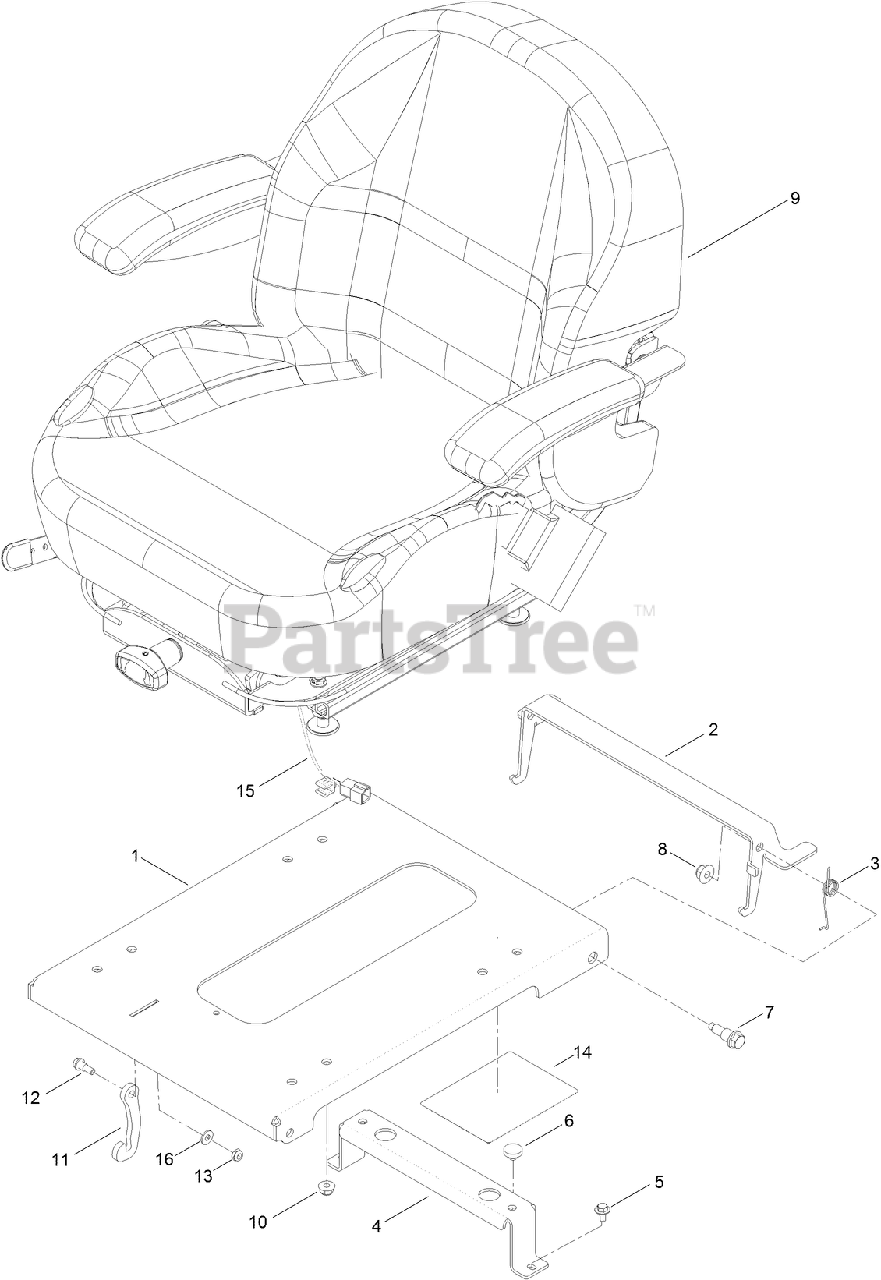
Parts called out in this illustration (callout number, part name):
1	SEAT PAN ASM
2	LATCH-SEAT
3	TORSION-SPRING
4	SEAT-SUPPORT, REAR
5	SCREW-HHFTF
6	BUMPER
7	BOLT-SHOULDER
8	NUT-HF, NI
9	SEAT-SUSPENSION
10	NUT-HF, NI
11	STOP-SEAT
12	BOLT-SHOULDER
13	NUT-LOCK, NI
14	DECAL-MAINTENANCE
15	HARNESS-WIRE
16	WASHER
